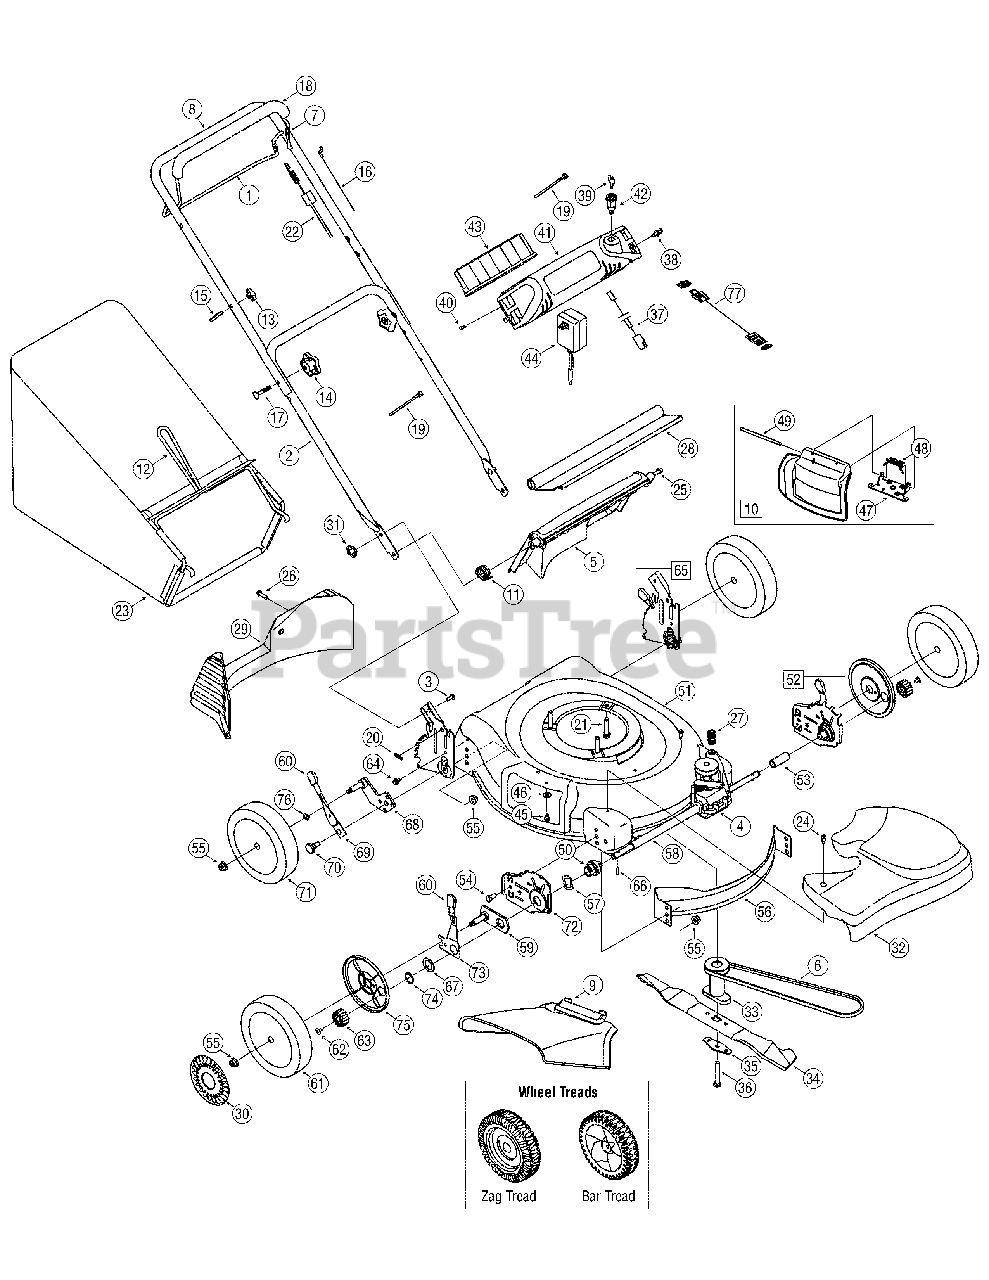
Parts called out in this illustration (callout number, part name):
1	Drive Control
3	Carriage Bolt 1/4-20
4	Transmission Assembly
5	Rear Discharge Door
6	V-Belt
9	Chute Deflector
10	Mulch Plug Complete
11	Torsion Spring - RH
13	Handle Knob
14	Handle Knob
15	Eye Bolt
16	Control Cable - 40.75"
16	Control Cable - 39"
16	Control Cable - 39" (Kawasaki)
17	Carriage Bolt 5/16-18 x 2.0
18	Bail Cover
19	Cable Tie
20	Cotter Pin
21	Self-Tapping Sems Screw
22	Drive Cable
23	Grassbag - Black
23	Grassbag - Gray
24	Shoulder Screw # 12 -24
25	Pivot Rod
26	Screw, 1/4-15 x 1.00
27	Belt Tension Spring
28	Rear Trailing Shield
29	Rear Baffle
30	Hub Cap
31	Wing Nut
32	Transmission Cover - Black
32	Transmission Cover - Gray
33	Blade Adapter
34	21" Mulching Blade
35	Blade Bell Support
36	Hex Screw 3/8-24 x 2.50
37	Electric Starter Harness
38	Rivet
39	Key
40	Screw, #10-16 x .75
41	Battery Housing
42	Key Switch
43	12 Volt Battery
44	Battery Charger
45	TT Screw 1/4-20 x 0.5
46	Bell Washer.265 x 0.75
47	Deflector Chute Adapter
48	Torsion Spring
49	Hinge Pin
50	Bearing Assembly
52	Height Adjustment Ass’y - LH
53	Slev. Spacer 1.4" Lg.
54	Hex Screw, 3/8-16 x.75
55	Flange Lock Nut, 3/8-16
56	Front Baffle
57	Wave Washer
58	Sleeve Spacer 8.985" Lg.
59	Pivot Plate Assembly
60	Adjustment Knob
61	Front Wheel, 8 x 1.8, Bar
61	Front Wheel, 8 x 2.125, Zag
62	Screw, 1/4-20 x .390
63	Gear 14T RH FWD
63	Gear 14T LH FWD
64	TT Scr. w/Washer 1/4-20 x.625
65	Handle Bracket Assembly - RH
65	Handle Bracket Assembly - LH
66	Dowel Pin
67	Washer
68	Pivot Arm Assembly - RH
68	Pivot Arm Assembly - LH
69	Rear Spring Lever
70	Shoulder Scr., 500 Dia. x. 434
71	Rear Wheel, 8 x 1.8, Bar
71	Rear Wheel, 8 x 2.125, Zag, w/BB
71	Rear Wheel, 8 x 2.125, Zag
72	Height Adjuster Plate - RH
72	Height Adjuster Plate - LH
73	Front Lever - RH
73	Front Lever - LH
74	Snap Ring
75	Wheel Dust Cap
76	Washer, Wave, .510 x .750 x .017
77	Extension Harness (Kawasaki)
